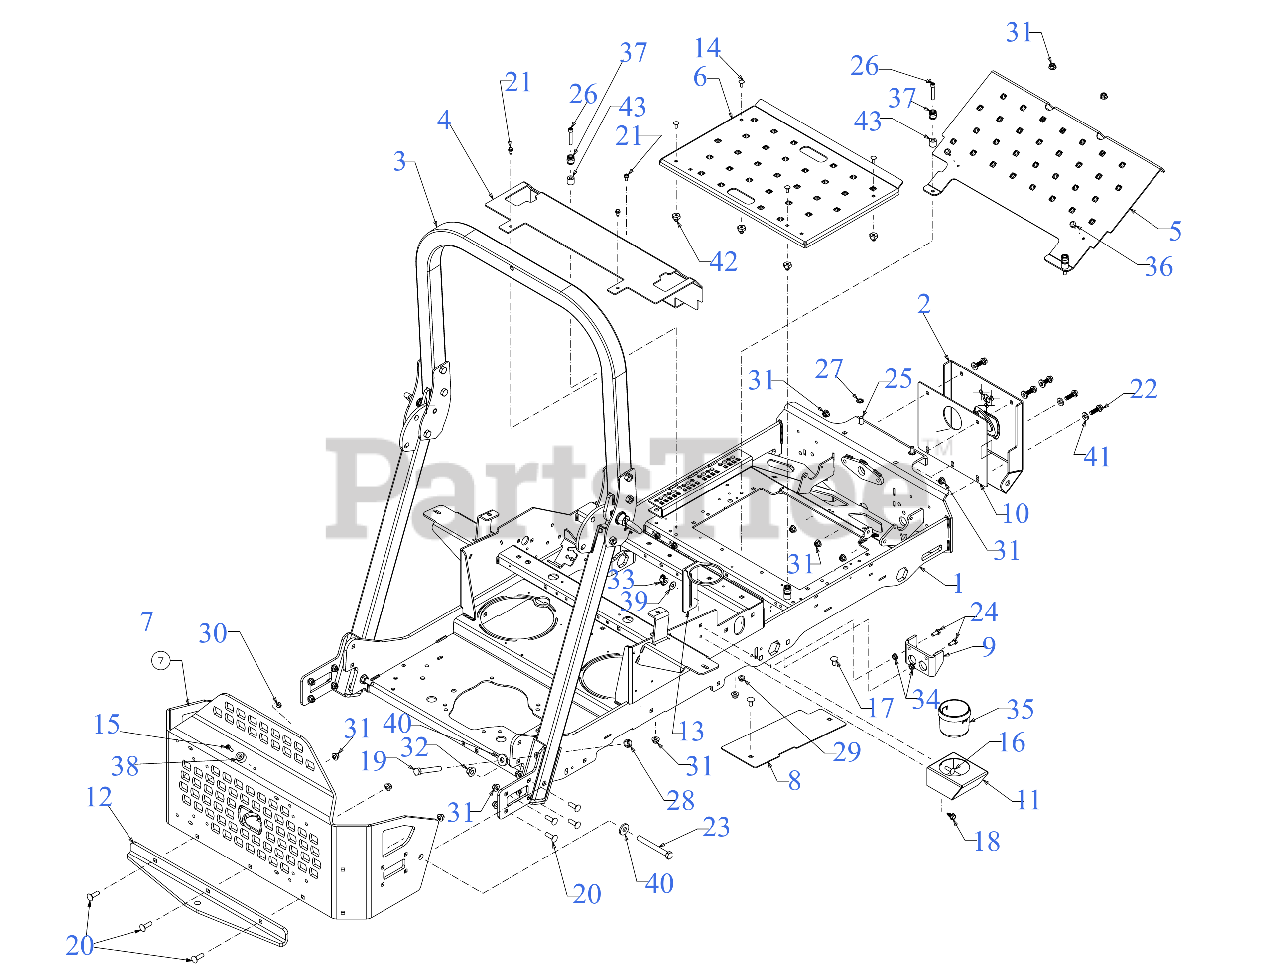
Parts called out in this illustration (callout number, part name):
3	PRO Z ROPS KIT
14	CARRIAGE BOLT 1/4-20 x .62
15	MACHINE SCREW 1/4-20:1
16	CARRIAGE BOLT 5/16-18 x 1.00
17	CARRIAGE BOLT 3/8-16 x .750 GR5
18	SCREW 5/16-18 x .750
19	SCREW 1/2-20 x 3.50 GR5
20	CARRIAGE BOLT 3/8-16 X1.25 GR5
21	SCREW 1/4-20 X.500
22	SCREW 3/8-16 x 1.25 GR5
23	SCREW 1/2-13 x 4.5 GR 5
24	SCREW 5/16-18 x .75 GR5
25	CARRIAGE BOLT 3/8-16 x 1.00 GR5
26	SCREW 5/16-18X1.75 GR5
28	HEX NUT CENTER
29	FLANGE LOCK NUT 5/16-18
30	FLANGE LOCK NUT
33	WING NUT 5/16-18
34	FLANGE NUT
36	BUMPER, .62 DIA x .3
37	RADIAL BUMPER
39	FLAT WASHER
40	FLAT WASHER .531 x 1.25 x .181
41	FLAT WASHER
42	SHOULDER SPACER
